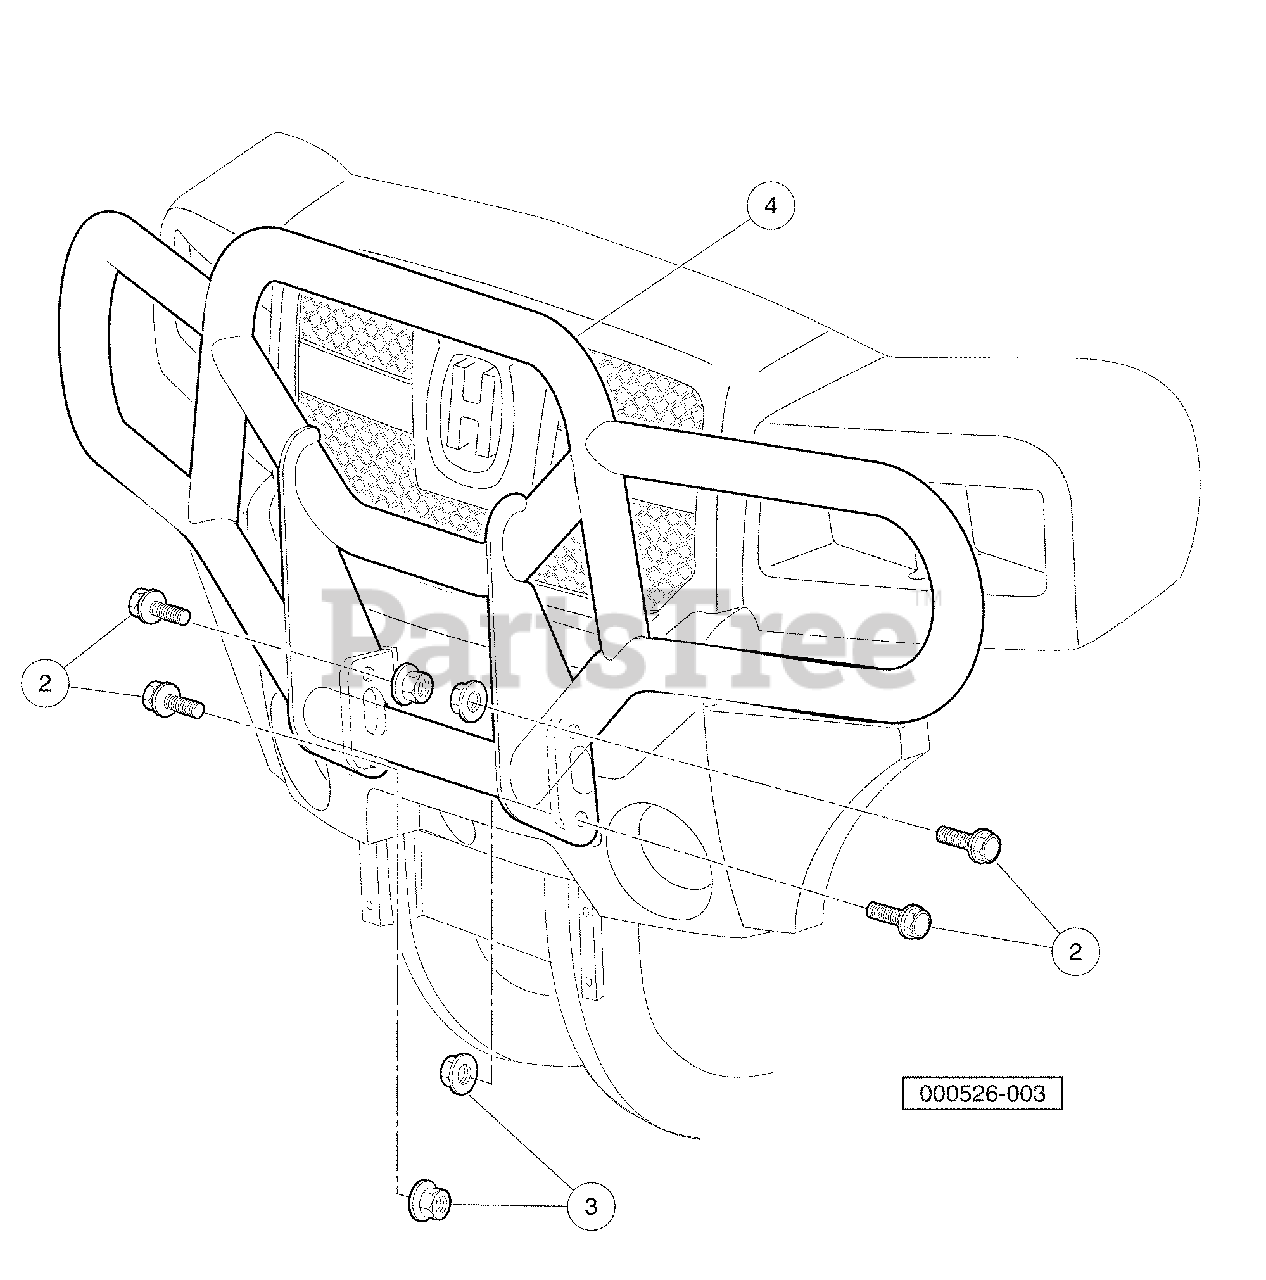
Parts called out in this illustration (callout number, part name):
1	Kit, Brush Guard Hus
2	Screw, M10 X 1.25 X 30 Hex Blk
3	Nut, Flg, M10 X 1.25 Hex Blk
4	Weldment, Brushguard, HUV 4421
